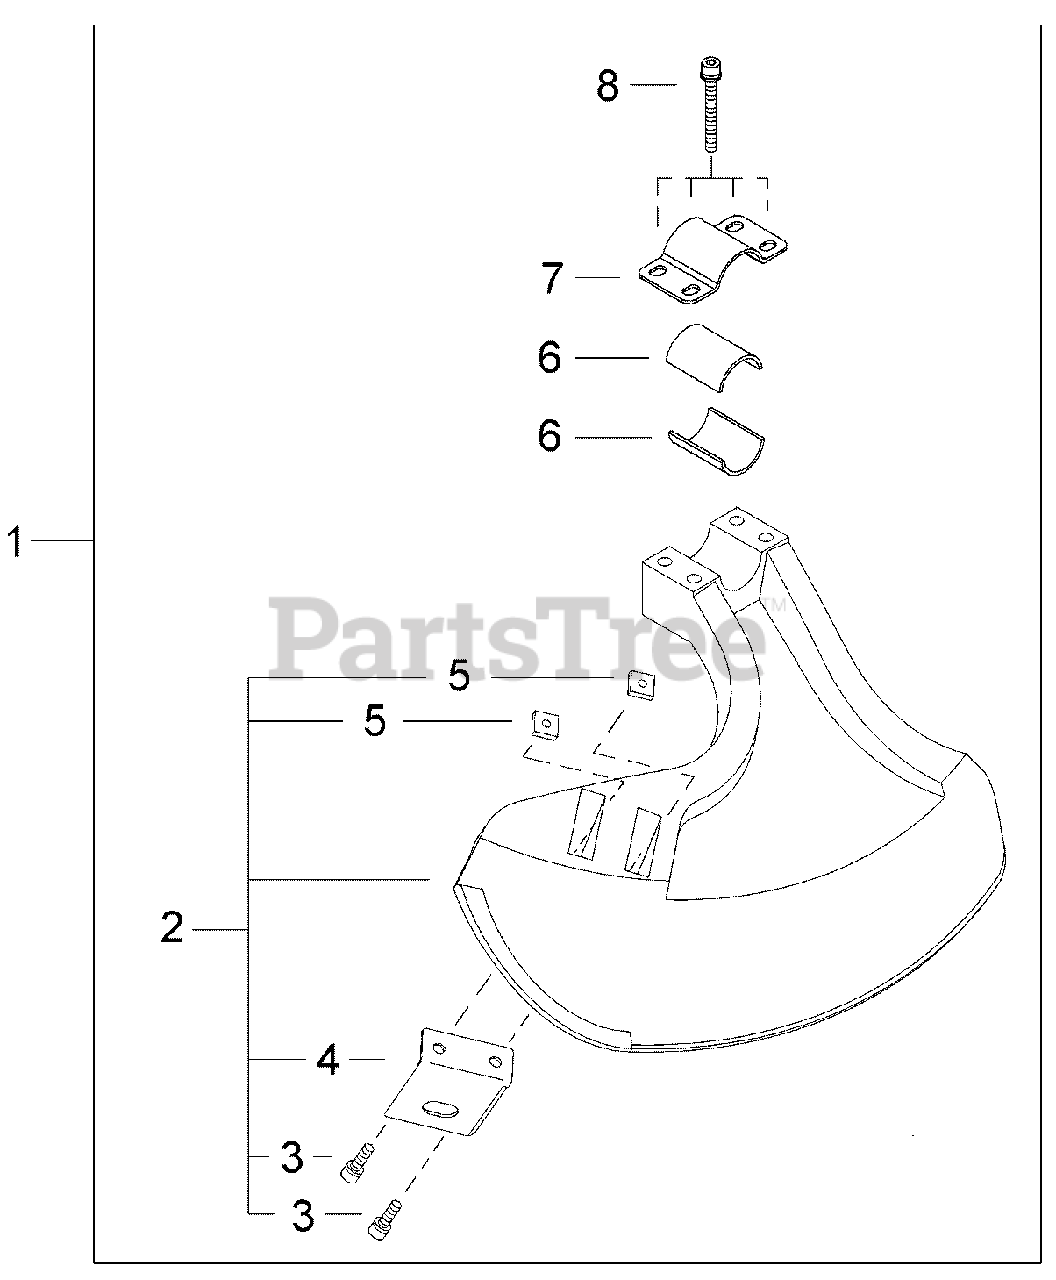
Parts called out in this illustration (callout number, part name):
1	DEBRIS SHIELD KIT
2	DEBRIS SHIELD ASSY
3	BOLT M5×16
4	CUTTER
5	NUT M5
6	SPACER
7	CLAMP, UPPER
8	BOLT M5×45
